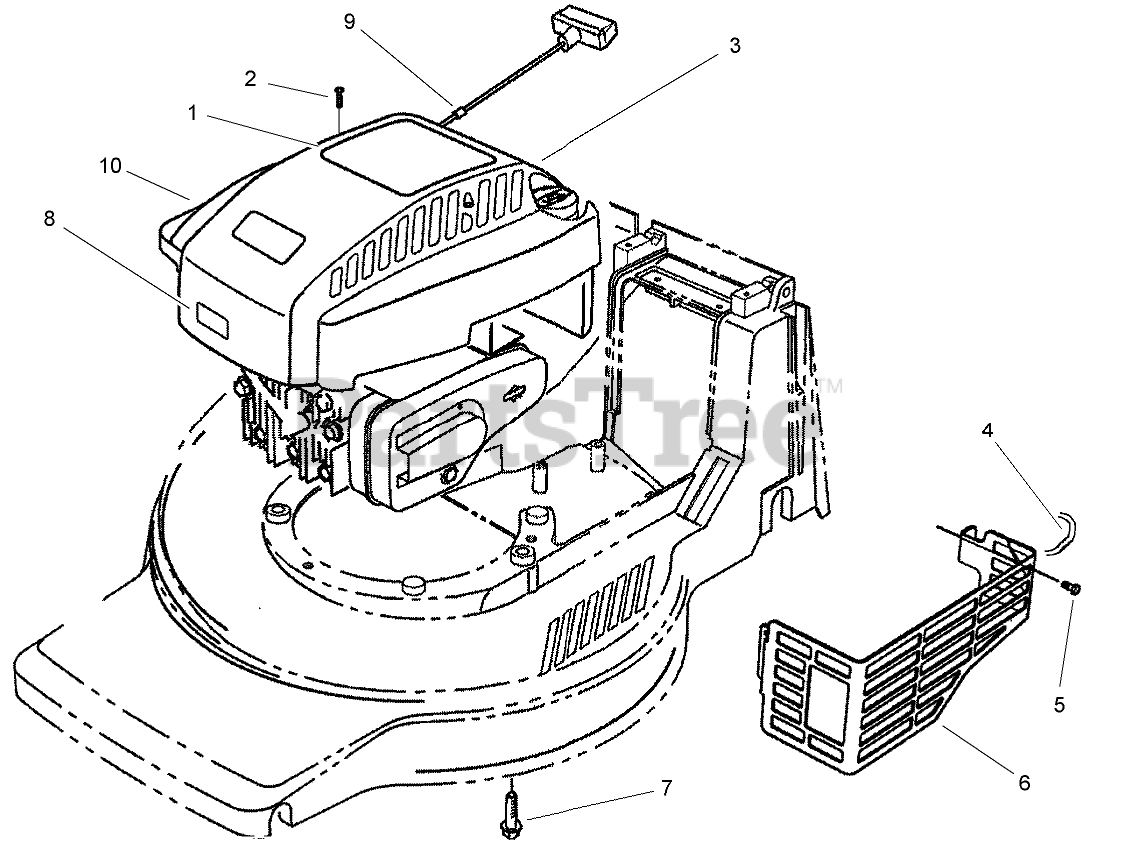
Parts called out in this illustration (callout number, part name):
1	Decal-Shroud
2	SCREW-PPH
3	SHROUD-ENGINE
4	TIE-CABLE
5	SCREW-HWH
6	SHIELD-MUFFLER
7	SCREW-HWH
8	Decal
9	STOP-ROPE
10	ENGINE
